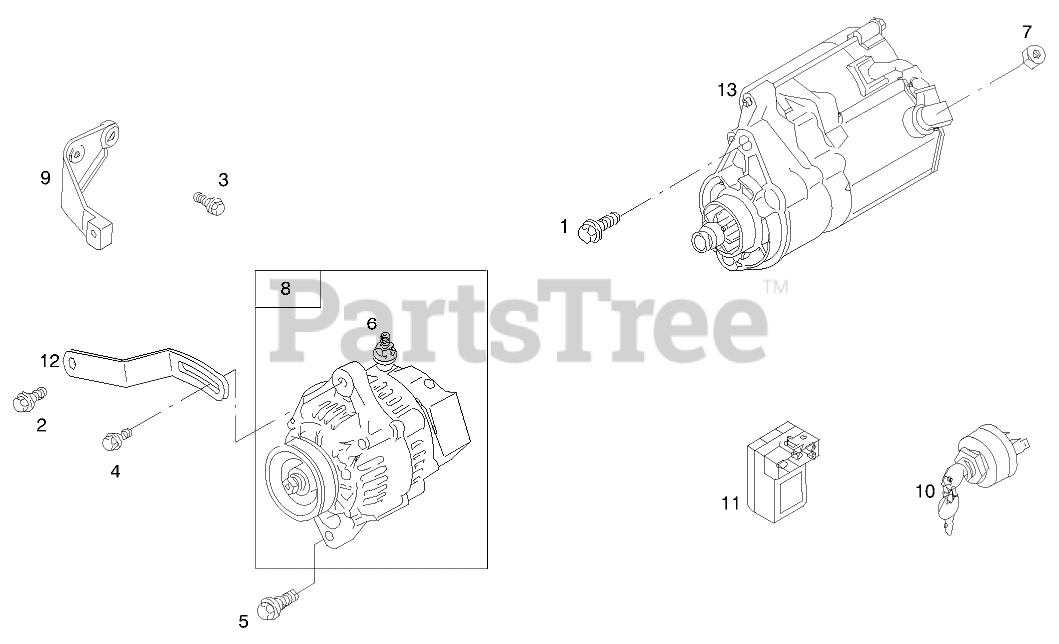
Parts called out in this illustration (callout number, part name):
1	SCREW-HEX
2	SCREW-HEX
3	SCREW-HEX
4	SCREW-HEX, METRIC
5	SCREW-HEX, METRIC
6	NUT-HEX, METRIC
7	NUT-HEX, METRIC
8	ALTERNATOR
8	SWITCH-TEMPERATURE, WATER
9	BRACKET-SUPPORT
9	GASKET-SET
10	KEY SWITCH
11	MODULE
12	BRACKET-ADJUSTING
13	MOTOR-STARTER
14	VALVE OVERHAUL KIT
15	SHAFT-GEAR
